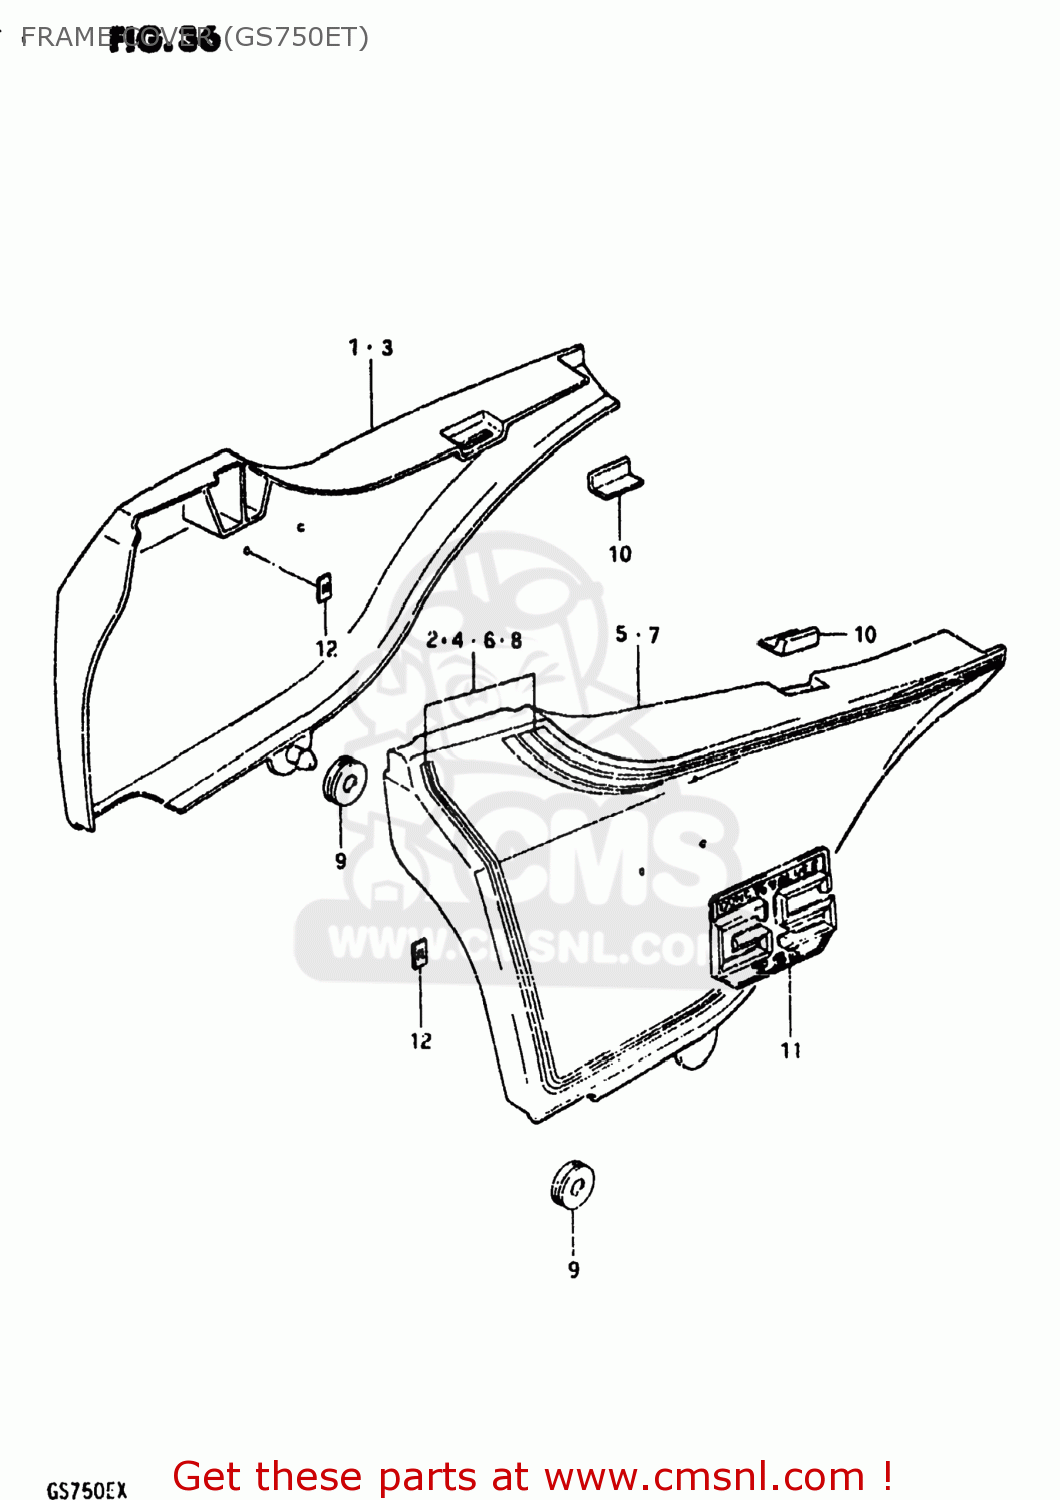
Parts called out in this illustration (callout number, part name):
1	COVER,FRAME,RIGHT
3	COVER,FRAME,RIGHT
4	TAPE SET,FRAME COVER
5	COVER,FRAME,LEFT
6	TAPE SET,FRAME COVER
7	COVER,FRAME,LEFT
8	TAPE SET,FRAME COVER
9	CUSHION
10	CUSHION,FRAME COVER
11	EMBLEM,FRAME COVER
12	NUT
